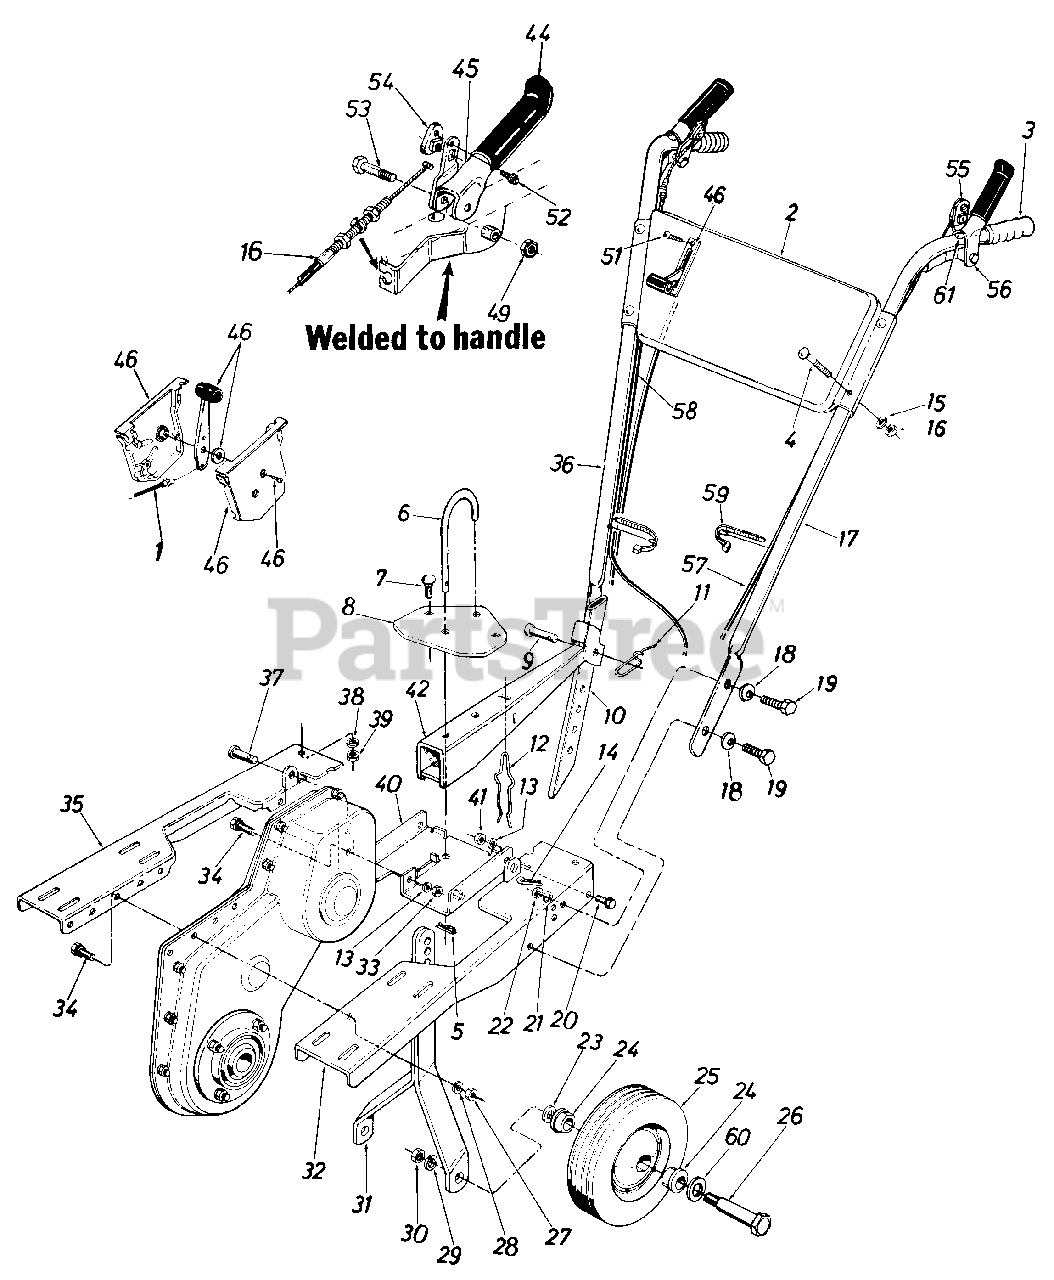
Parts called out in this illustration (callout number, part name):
1	WIRE-CONTROL
2	PANEL-HANDLE
3	GRIP-BLACK
4	BOLT-CARRIAGE 5/16-18 x 1.75
5	PIN-COTTER
6	PIN-CLEVIS .50 DIA
7	BOLT-CARRIAGE 5/16-18 x .75
8	PLATE-U CHANNEL
9	PIN-CLEVIS
10	BAR-DEPTH
11	PIN-SPRING
12	SPRING-DEPTH BAR
13	WASHER-LOCK-5/16
14	PIN-COTTER
15	WASHER-LOCK-5/16
16	NUT-HEX 5/16-18
17	HANDLE-LH
18	WASHER-BELL .400 ID x .88 x .060
19	SCREW-HEX 3/8-16 x 1.00
20	SCREW-HEX 5/16-18 x .75
21	WASHER-LOCK-3/8
22	NUT-HEX 3/8-16
23	WASHER-BELL .505 ID x 1.00 OD
24	BEARING-FLANGE
25	WHEEL ASSY-10 x 1.75
26	SCREW-SHLD
27	NUT-HEX 5/16-18
28	WASHER-LOCK-5/16
29	WASHER-LOCK-1/2
30	NUT-HEX INS L-1/2-20
31	BRACKET ASSY-WHL
32	CHANNEL ASSY-U-LH
33	NUT-HEX 5/16-18
34	CHANNEL-ENG U
35	CHANNEL-ENG U
36	HANDLE ASSY-RH
37	PIN-CLEVIS
38	WASHER-LOCK-5/16
39	NUT-HEX 5/16-18
40	BRACKET ASSY-U CHANNEL
41	NUT-HEX 5/16-18
42	TAIL PIECE ASSY
45	GRIP ASSY-CLUTCH-RH
46	CONTROL BOX-THROTTLE
49	NUT-HEX INS L-3/8-24
51	SCREW-TRUSS TAP
52	SCREW-TAP
53	SCREW-HEX 3/8-24 x 2.00
54	HOLD DOWN-BARREL-RH
55	HOLD DOWN-CABLE
56	GRIP ASSY-LH
57	CABLE-CLUTCH CONTROL
58	CABLE-CLUTCH CONTROL
59	TIE-CABLE
60	WASHER-FL-.640ID x 1.24OD x .06HDN
61	CAP-PUSH
